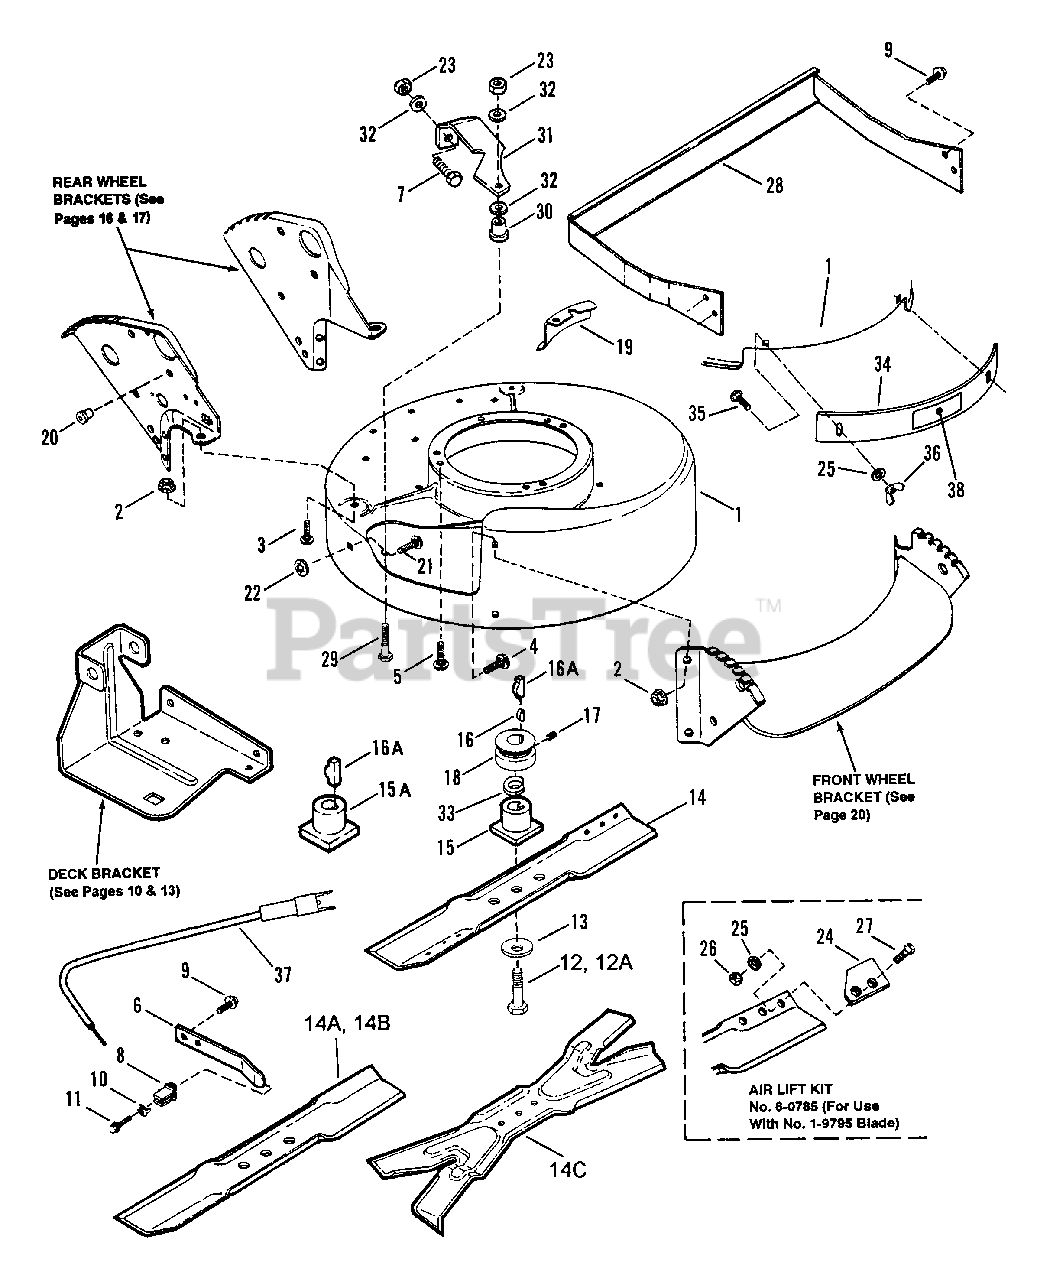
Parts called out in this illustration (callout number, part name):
1	DECK, Mower
2	NUT, 5/16-18 Hex Flange Lock, Grade 5
3	BOLT, 5/16-18 x 1/2" Short Neck Carriage (Gr. 5)
4	BOLT, Bolt 5/16-18 x 1-1/8" Short Neck Carriage, Grade 5
5	SCREW, 3/8-16 x 1" Self-Tapping (Engine Mounting)
6	SPRING, Wheel Bracket Type Interlock
7	SCREW, 5/16-18 x 1/2" Hex Head Cap, Grade 5
8	INSULATOR, Interlock
9	SCREW, 1/4-20 x 1/2" Hex Self-tapping
10	WASHER, #8 Tab Internal Tooth Lock
11	SCREW, #8-18 x 3/4" Hex Head Machine
12	SCREW, 3/8-24 x 2" Hex Head Cap, Grade 5
12A	SCREW, 3/8-24 x 1-3/4" Hex Head Cap, Grade 5
13	WASHER, Cone
14	BLADE, Cutter
14A	BLADE, Cutter
14B	BLADE, Cutter
14C	BLADE, Cutter (Ninja - Quad Edge)
15	HUB, Blade Drive 25mm
15A	HUB, Blade Drive 7/8"
16	KEY, Woodruff #506
16A	KEY, Woodruff #505
17	SCREW, 5/16-18 x 5/16" Hex Socket Set
18	PULLEY, Engine (25mm I.D. x 2-1/8" O.D.)
18	PULLEY, Engine (7/8" I.D. x 2-1/4" O.D.)
19	SHIELD, Belt Opening Cover
20	BUSHING, Interlock Wire
21	BOLT, 5/16-18 x 3/4" Short Neck Carriage, Grade 5
22	RETAINER, 5/16 Bolt
23	NUT, 5/16-18 Hex, Grade 5
24	LIFT, Air
25	WASHER, 5/16 Internal Tooth Lock
26	NUT, 5/16-24 Hex, Grade 5
27	SCREW, 5/16-24 x 21/32" Machine
28	STRUCTURE, Fender
29	BOLT, 5/16-18 x 2-1/4" Hex Flange Lock
30	BUSHING
31	COVER, Belt
32	WASHER, 5/16 Split Lock
33	SPACER, Blade Hub
34	BAFFLE, Front
35	BOLT, 5/16-18 x 5/8" Carriage, Gr. 5
36	NUT, 5/16-18 Flange Lock, Grade 5
37	WIRE, Ground
38	DECAL, Front Baffle
